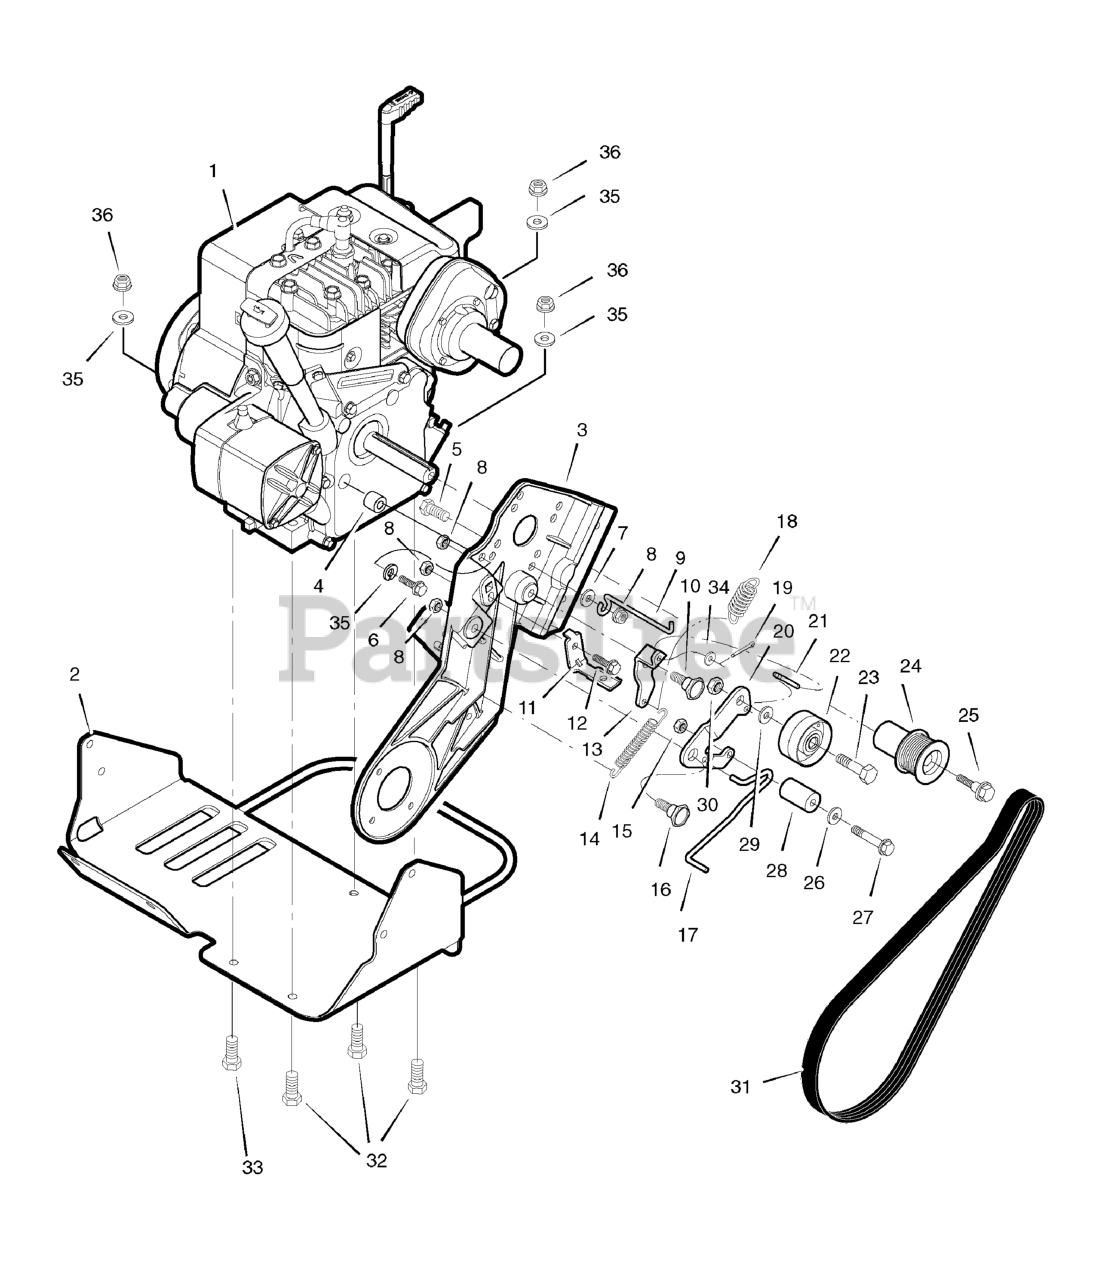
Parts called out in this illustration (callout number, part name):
1	ENGINE, 5HP 4CY B&S Recoil Start *
1	ENGINE, 5HP 4CY B&S Electric Start *
2	CRADLE ASSEMBLY, Engine
4	ANTI-VIBRATION MOUNT, Engine
5	BOLT, Hex, 5/16 - 18
6	BOLT, Hex, 5/16 - 24
7	WASHER, Flat
8	NUT, Hex Center Lock, 5/16 - 18
9	GUIDE, Belt
10	BOLT
11	PAD, Brake
12	SCREW, 1/4 - 20 x 5/8
13	IDLER, Arm Pivot
15	NUT, Hex 1/4 - 20
16	BOLT
17	WIRE, Brake
18	SPRING
19	PIN, Cotter
20	ARM, Idler
21	ROD, Clutch Linkage
22	PULLEY, Idler
23	SCREW, 3/8 - 16 x 1-1/2
24	PULLEY, Engine
25	BOLT, Engine Pulley
26	WASHER, Flat
27	SCREW, 1/4 - 20 x 2
28	PINCH ROLLER
29	WASHER, Flat
30	NUT, Hex
31	BELT, Drive
32	BOLT, Hex, 5/16 - 18
33	SCREW, 3/8 - 16 x 1
34	WASHER, Flat
35	LOCKWASHER, Split
36	NUT, 5/16 - 18
